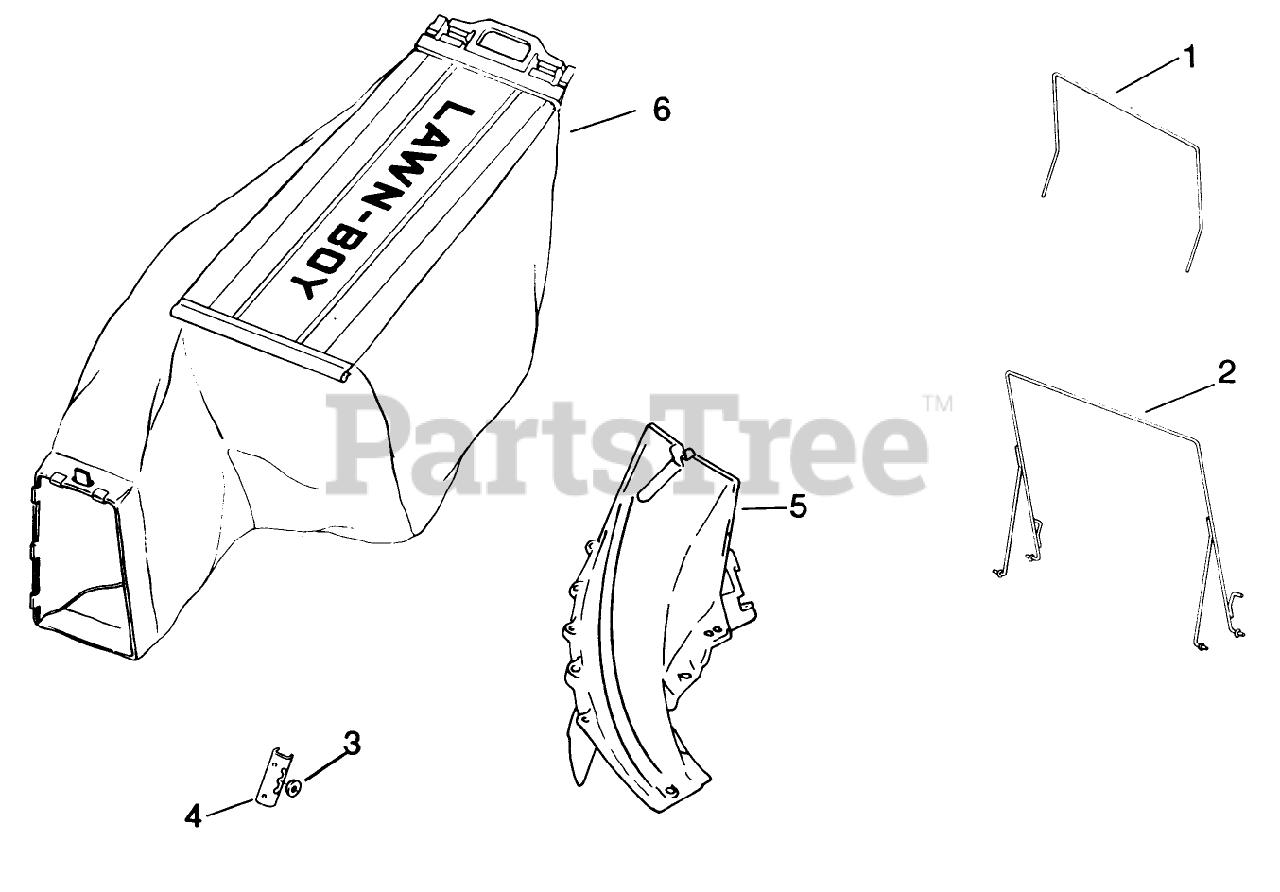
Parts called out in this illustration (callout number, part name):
1	HANGER
3	WASHER-CURVED
4	BRACKET R/B 613462
